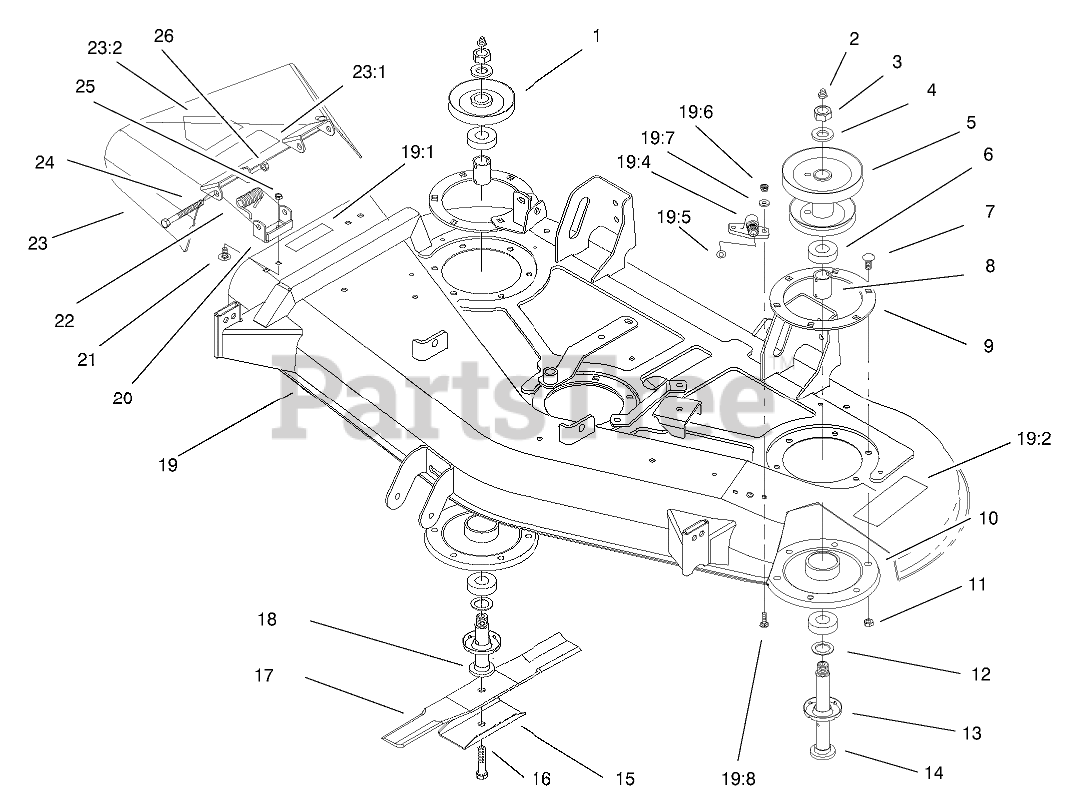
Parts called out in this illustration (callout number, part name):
1	PULLEY
2	FITTING-GREASE
3	NUT-JAM
4	WASHER-FLAT
5	PULLEY-DOUBLE
6	BEARING-BALL
7	SCREW-CARR
8	SPACER-BEARING
9	RING-DECK SUPPORT
10	HOUSING-SPINDLE
11	NUT-HF
12	WASHER-BACKUP
13	SHIELD-BEARING
14	SHAFT - SPINDLE
15	STIFFENER-BLADE
16	SCREW-BLADE
17	Blade
18	SHAFT-SPINDLE
19	DECK ASM
19:1	DECAL-DANGER
19:2	DECAL-DANGER
19:4	FITTING-WASHOUT
19:5	O-RING
19:6	NUT-LOCK, NI
19:7	WASHER-FLAT
19:8	BOLT-CARR
20	BRACKET-PIVOT
21	SCREW-CARR
22	SPRING
23	DEFLECTOR ASM
23:1	DECAL-DANGER
23:2	DECAL-DANGER
24	SCREW-HH
25	NUT-LOCK, NI
26	NUT-HEX
